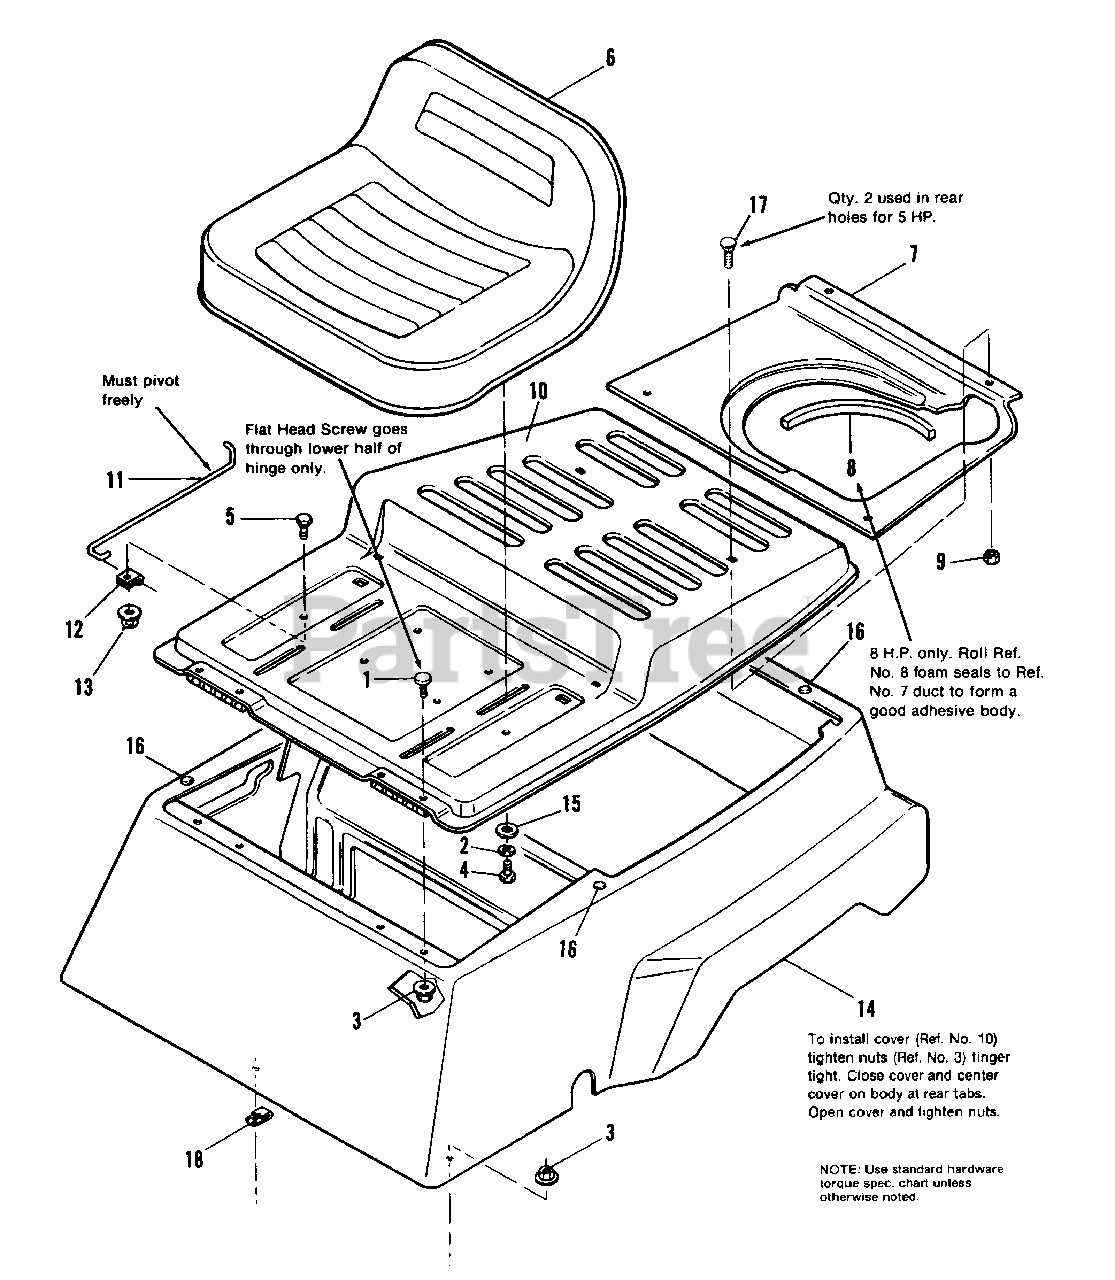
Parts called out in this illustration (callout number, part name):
1	SCREW, Flat Hd., 5/16-18 x 7/16
2	LOCKWASHER, 5/16
3	LOCKNUT, Flange, Whiz, 5/16-16
4	CAPSCREW, 5/16-18 x 5/8
5	CAPSCREW, Hex, 1/4-20 x 1/2
6	SEAT, (5 HP)
7	DUCT, Inlet (8 & 10 HP Only)
8	SEAL, Foam (8 HP Only)
9	PALNUT, #10-24 (Qty. 2 on 5 HP)
10	COVER ASSY.
11	ROD, Cover Support
13	LOCKNUT, Flange, 1/4-20
14	BODY ASSY.
15	WASHER, Plain, 5/16
16	PLUG, Bumper
17	BOLT, Carriage, #10-24 x 1/2 (Qty. 2 on 5 HP)
18	NUT, Speed, 5/16-18 (Oty. 2 on 5 HP)
